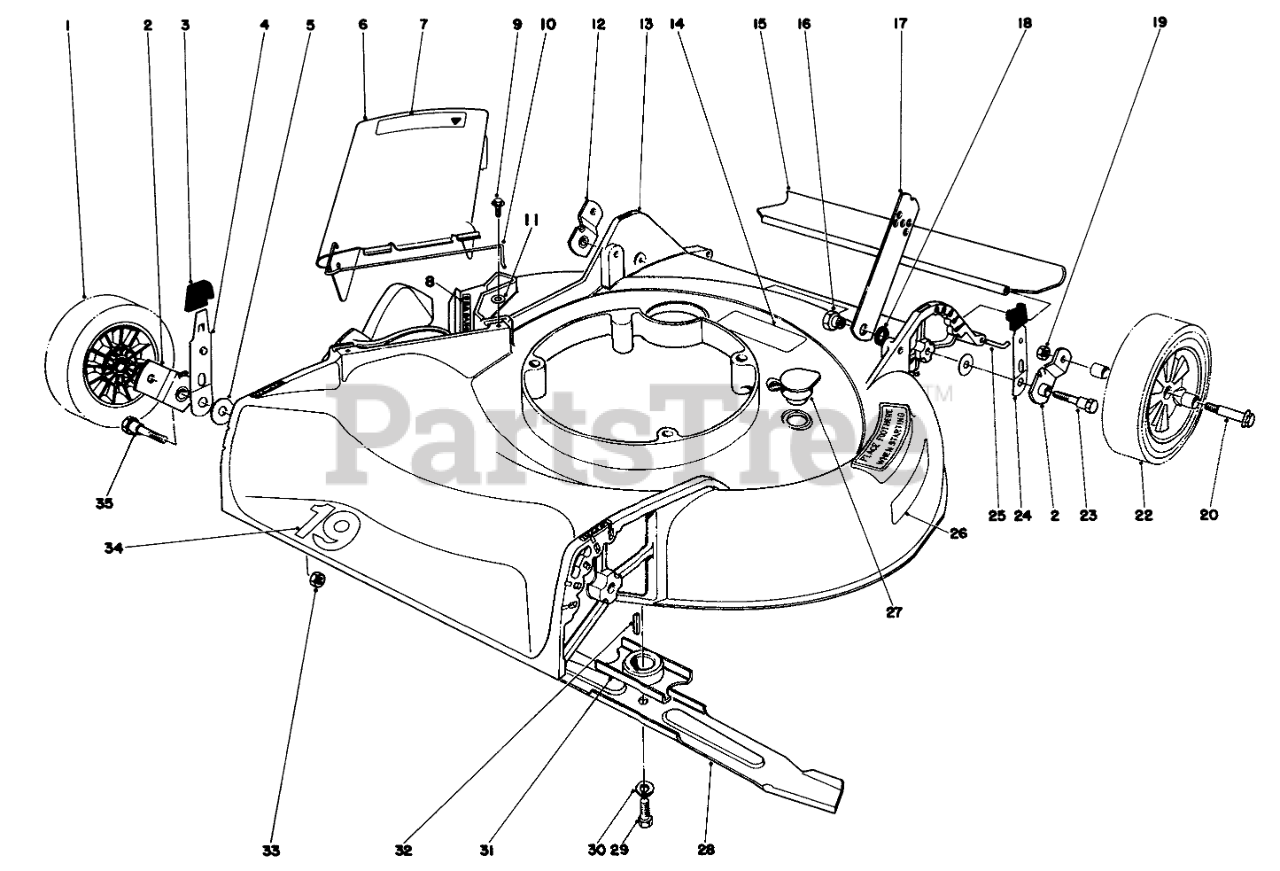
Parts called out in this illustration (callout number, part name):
1	WHEEL TIRE ASM 7 IN
2	Pivot Arm
3	KNOB-ARM
4	SPRING ARM ASM
5	WASHER-PIVOT
6	Deflector-Cover Assembly (Incl. Ref. #7 & 10)
7	Decal-Caution
8	Decal-Danger
9	SCREW
10	SPRING HINGE
11	WASHER-FLAT
12	Pivot Arm
13	Housing (Model 16077)
14	Decal-Warning
15	SHIELD - TRAILING
16	HANDLE PIVOT NUT
17	Handle Latch
18	HANDLE LATCH SPACER
19	Nut
20	BOLT-WHEEL
22	WHEEL TIRE ASM 8 IN
23	PIVOT SCREW
24	SPRING ARM ASM
25	SHIELD ROD
26	Decal-Step
27	WASHOUT PLUG
28	Blade
29	SPECIAL SCREW
30	WASHER-LOCK
31	Blade Retailer
32	KEY-SQUARE
33	Nut
34	Decal-19" (Model 16077)
35	PIVOT SCREW
